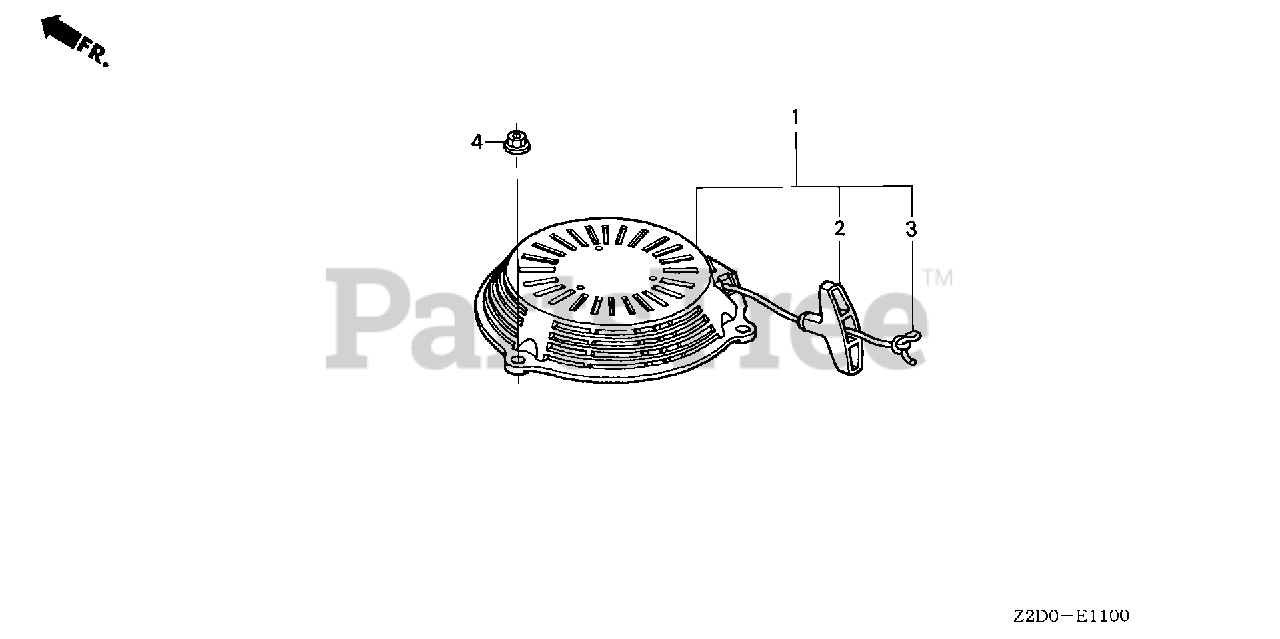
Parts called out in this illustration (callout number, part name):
1	STARTER ASSY., RECOIL *R280* (POWER RED)
1	STARTER ASSY., RECOIL *NH1* (BLACK)
2	GRIP, STARTER
3	ROPE, RECOIL STARTER (LONG TYPE)
4	NUT, FLANGE (6MM)
